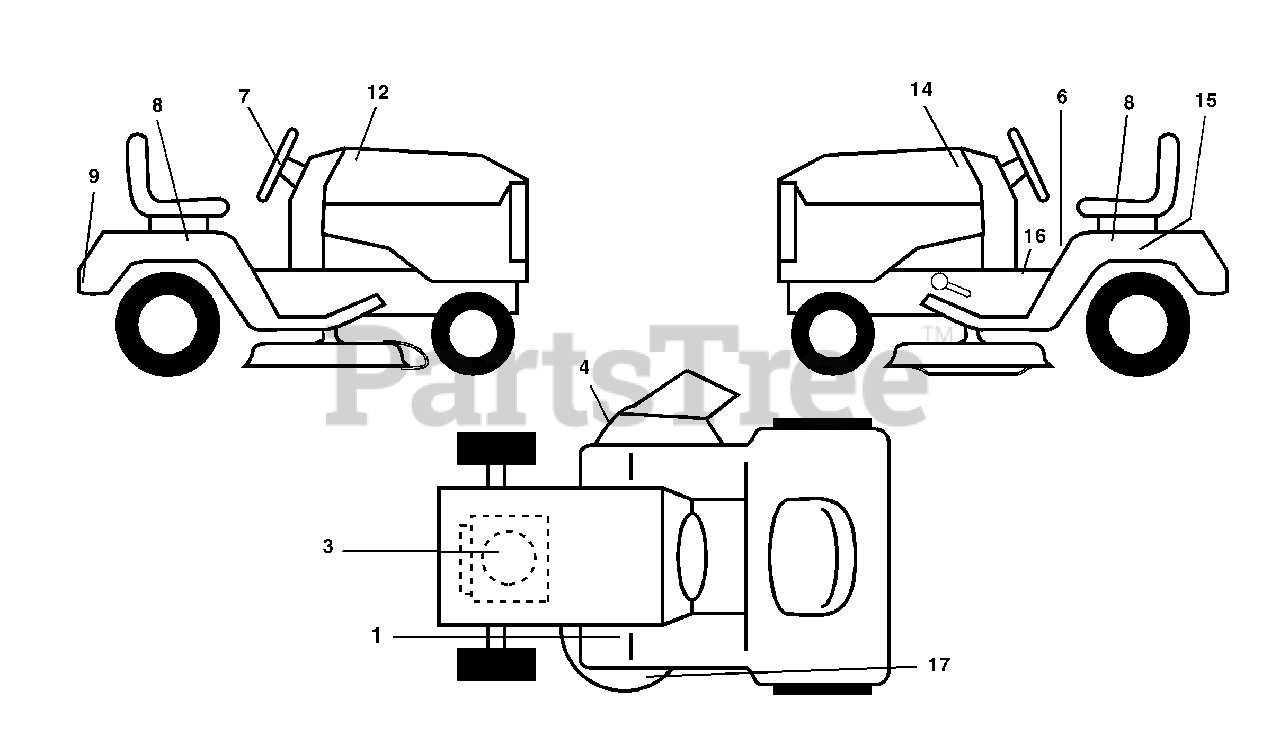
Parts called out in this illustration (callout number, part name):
1	Decal, Clutch/Brake Eng/Fr
3	Decal, Engine HP
4	Decal Warning
6	Decal, Fender Danger English
7	Decal Ins Str Wh
8	Decal, Fender 5 Sp.
9	Decal Fender
12	Decal, Hood RH
14	Decal, Hood LH
15	Decal, Caution, Battery
16	Decal, Oper Sdl P/L Gear Dr Eng
17	Decal, V-Belt Sch.
